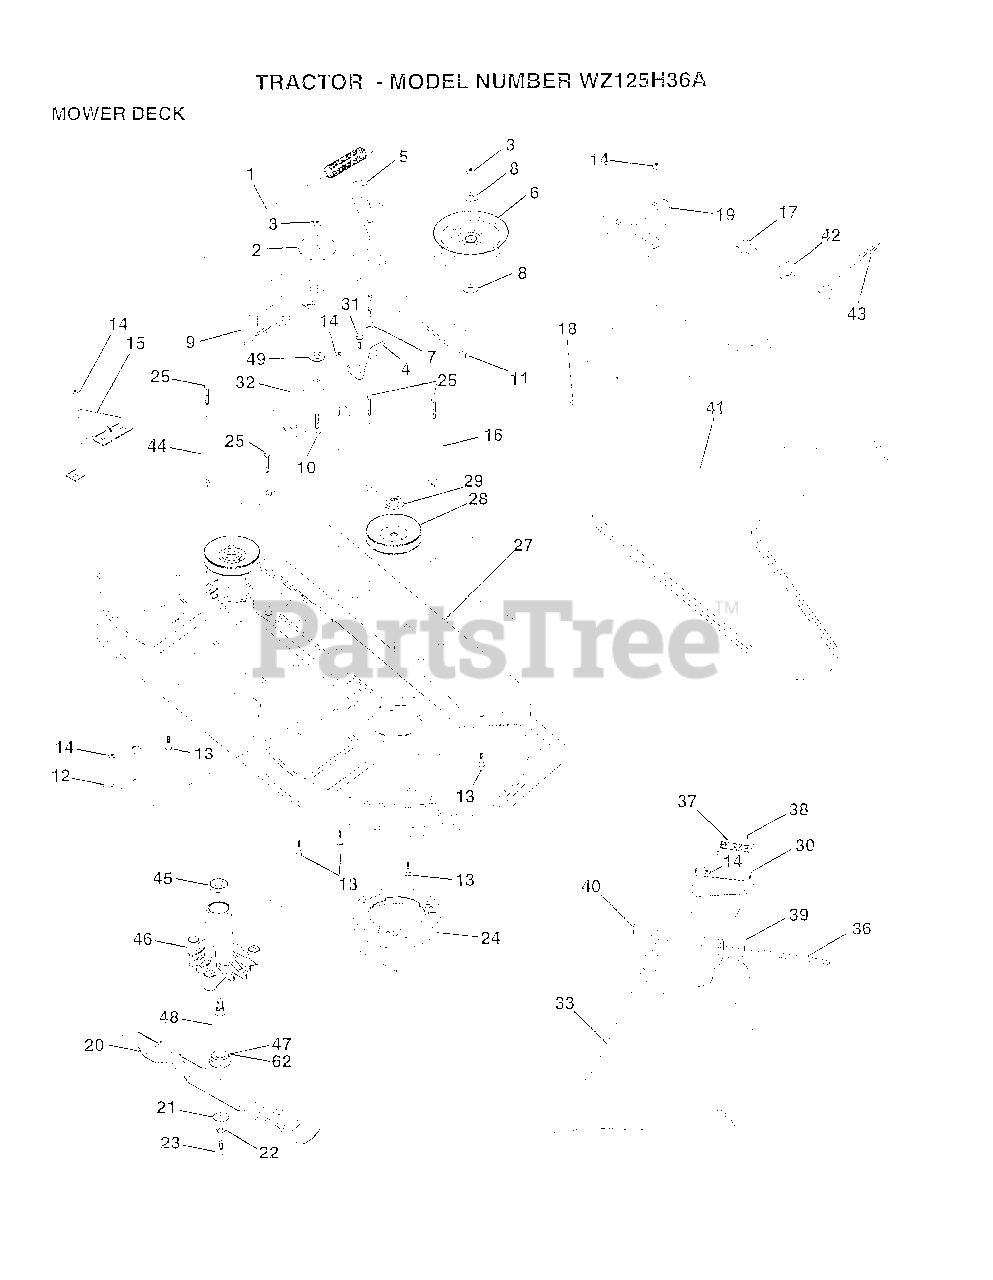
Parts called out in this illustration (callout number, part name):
1	SPRING CLUTCH MWR
2	SPACER RETAINER
4	BRAKE ASM
5	IDLER BELT GUIDE
6	PULLEY IDLER
7	BOLT
8	WASHER
10	BOLT.3/8-14X1.25
11	BRAKE ROD
12	"BRKT,LIFT REAR"
13	BOLT
15	"BRKT,LIFT REAR LH"
16	"KEEPER-BELT,RH"
17	MOWER LINK STAB
18	"PIN,GROOVE"
19	"BRKT,LINK STABILI"
20	"BLADE.36"" HIPERF"
21	WASHER.HARD.BLADE
23	BLADE BOLT
24	STRIPPER RND MWR
25	"SCREW-THD ROLL,WA"
27	"HOUSING-MOWER,36"""
28	PULLEY.MAND.36/46
31	SCREW LT
32	"SUPT,IDLER ARM"
36	HINGE ROD
37	SPRING TORSION
38	CAP-SLEEVE LT
39	WASHER
41	V-BELT.PRIM.78.5.
43	RETAINER.SPRING
44	KEEPER BELT LH
45	BEARING
46	HSG ASM MANDREL
47	BEARING.BALL
49	HARDENED WASHER
62	WASHER.FELT.
